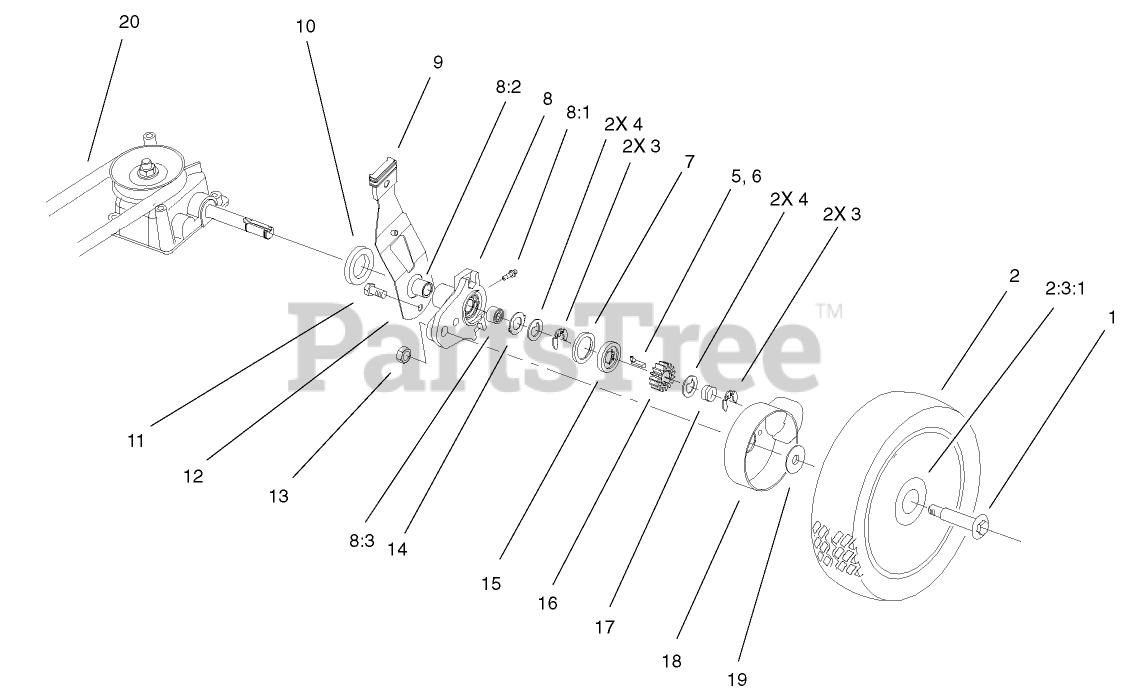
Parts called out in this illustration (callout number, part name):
1	BOLT-SHOULDER
2	WHEEL ASM
2:3:1	BUSHING
3	RING-RETAINING,CLIP
4	WASHER-THRUST, KEYED
5	KEY-ROCKING, RH
6	KEY-ROCKING, LH
7	RING-FRICTION
8	REAR HEIGHT ADJUSTMENT ARM ASM
8:1	FITTING-GREASE
8:2	BUSHING
8:3	BUSHING
9	KNOB-LEVER, HEIGHT ADJUSTMENT
10	SPACER-SHAFT, AXLE
11	SCREW-HWH
12	REAR SPRING ARM ASM
13	LOCKNUT
14	WASHER-ARM, PIVOT
15	WASHER-CLUTCH
16	GEAR-PINION
17	SPRING-COMPRESSION
18	COVER-WHEEL
19	WASHER-STEPPED
20	V-BELT
